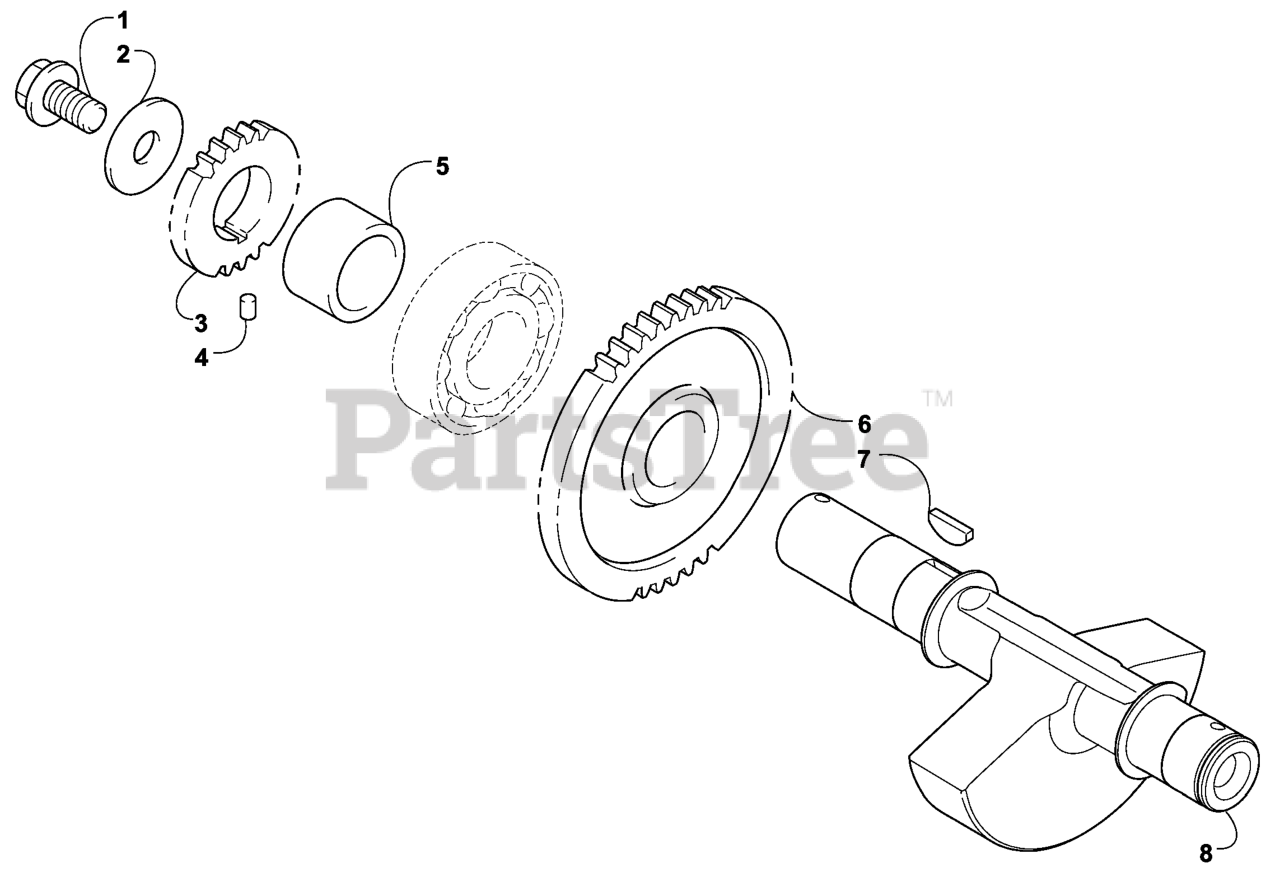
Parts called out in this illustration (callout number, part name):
1	SCREW-HFH
2	WASHER-STEEL
3	GEAR-DRIVEN, OIL AND WATE
4	DOWEL-SOLID
5	SPACER-DRIVE GEAR
6	GEAR-SHAFT, DRIVEN BALANC
7	WOODRUFF
8	BALANCER-CRANK
